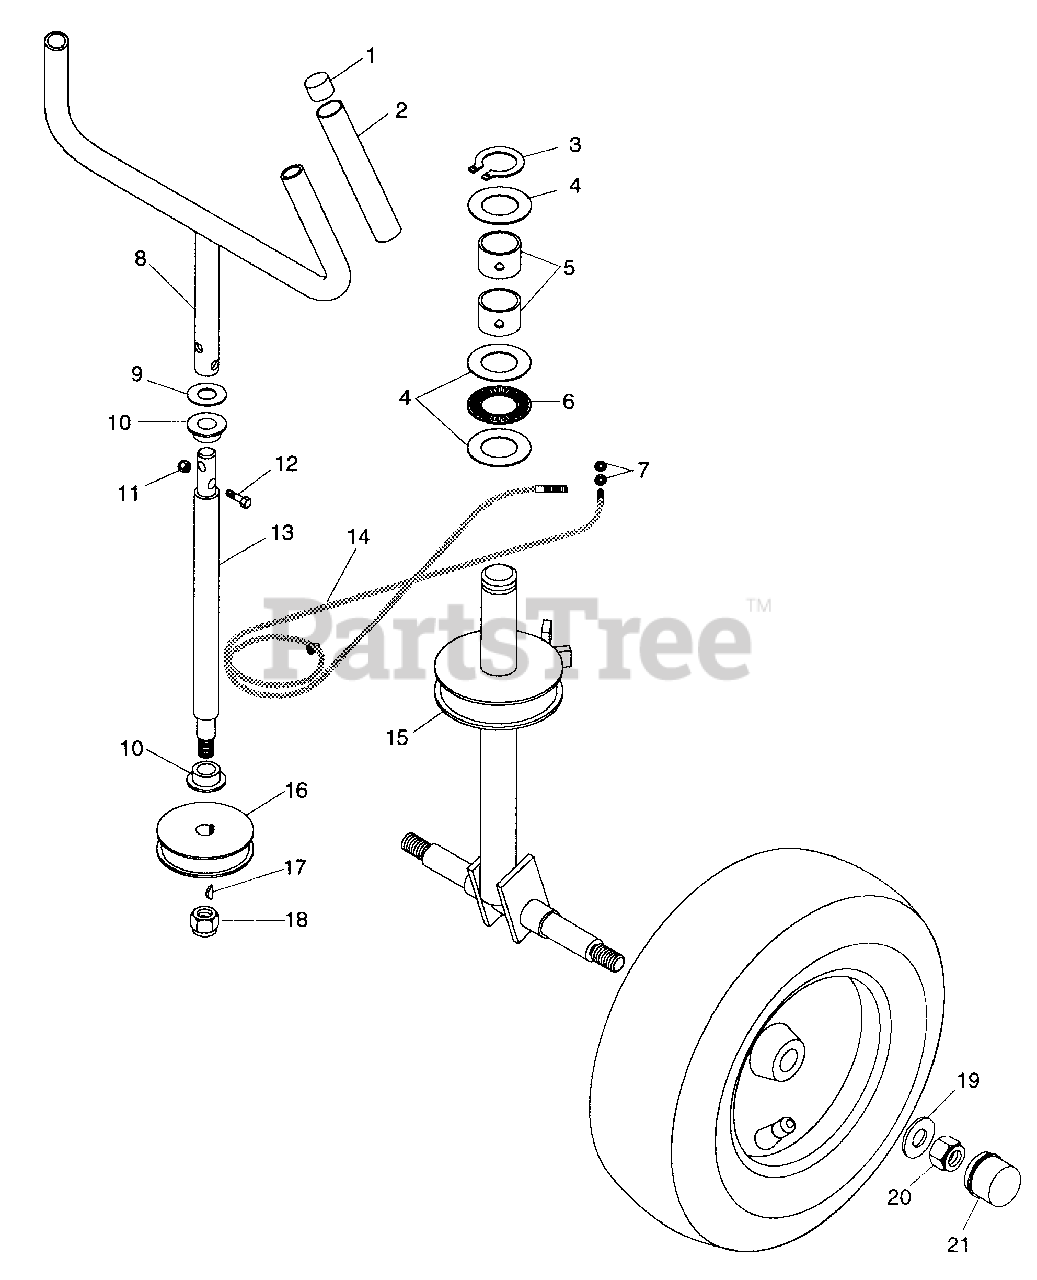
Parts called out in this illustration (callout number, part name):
1	Closure, Vinyl
2	Grip
3	Ring-Retaining-External 1.5 x 1.38
4	Washer-Thrust 1.502 x 2.18 x .063
5	Bearing 1.000 x 1.135 x 1.002
6	Bearing-Needle-Thrust 1.50 x 2.187 x .0781
7	Nut-Jam .312-18
8	Weldment, Handlebar
9	Bearing-Needle-Thrust .752 x 1.24 x .093
10	Bushing-Flange 1.020 x 1.385 x .75 x 1.75
11	Nut-Locking-Nylon .250-20
12	Bolt-Hex .25-20 x 1.38
13	Shaft
14	Cable, Steering
15	Weldment, Caster Wheel
16	Pulley, Cable
17	key, Woodruff 3/16 x 7/8
18	Nut, Lk 5/8-11 Hex
19	Washer-Flat .812 x 1.469 x .134
20	Nut-Locking-Nylon .75-10
21	Cap, Dust
